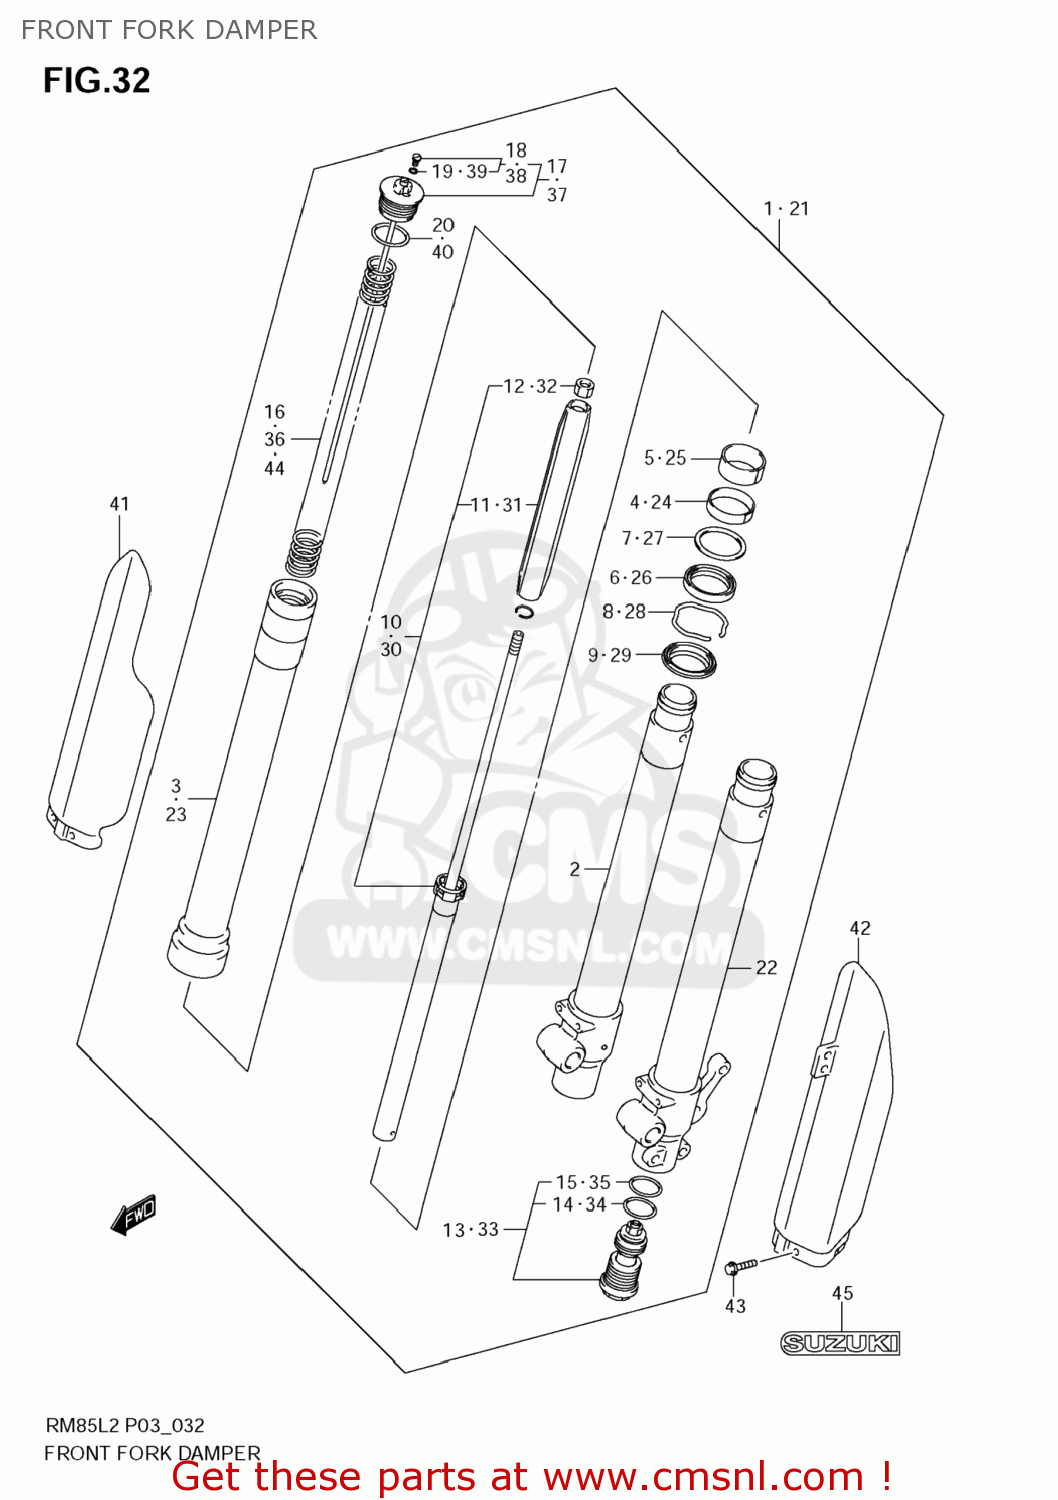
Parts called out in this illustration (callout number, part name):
1	DAMPER ASSY,FR FORK,R
2	TUBE,INNER,R
3	TUBE,OUTER
4	BUSH,GUIDE
5	BUSH,SLIDE
6	OIL SEAL,FRONT FORK
7	SPACER,SEAL
8	RING,STOPPER
9	SEAL,DUST
10	CYLINDER
11	GUIDE,SPRING
12	NUT
13	BOLT,CTR
14	O RING
15	O RING
16	SPRING,FR(K=0.28)
17	BOLT,FORK
18	BOLT,PLUG
19	O RING
20	O RING
21	DAMPER ASSY,FR FORK,L
22	TUBE,INNER,L
23	TUBE,OUTER
24	BUSH,GUIDE
25	BUSH,SLIDE
26	OIL SEAL,FRONT FORK
27	SPACER,SEAL
28	RING,STOPPER
29	SEAL,DUST
30	CYLINDER
31	GUIDE,SPRING
32	NUT
33	BOLT,CTR
34	O RING
35	O RING
36	SPRING,FR(K=0.28)
37	BOLT,FORK
38	BOLT,PLUG
39	O RING
40	O RING
41	PROTECTOR,FR FORK,R
42	PROTECTOR,FR FORK,L
43	BOLT(6X10)
44	SPRING,FR(K=0.26)
45	EMBLEM,SUZUKI
